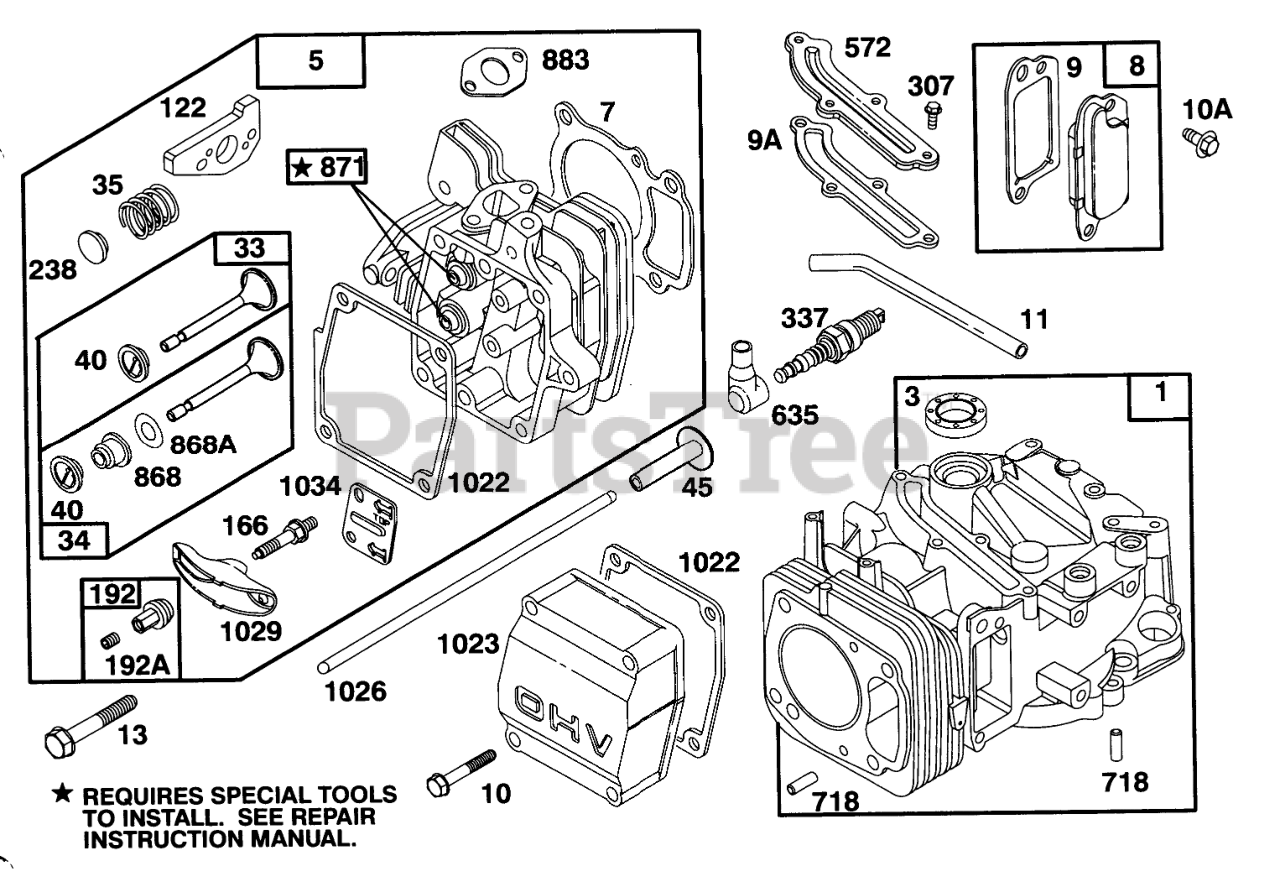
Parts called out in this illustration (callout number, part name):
1	CYLINDER ASSEMBLY
3	SEAL - OIL
5	CYLINDER HEAD
7	CYLINDER HEAD GASKET
8	BREATHER ASM
9	BREATHER GASKET
9A	GASKET-BREATHER
10	HEX HEAD SCREW
10A	HEX HEAD SCREW
11	TUBE - BREATHER
13	CYLINDER HEAD SCREW
33	EXHAUST VALVE
34	INTAKE VALVE
35	VALVE SPRING
40	SPRING RETAINER
45	VALVE TAPPET
122	ADAPTER ASSEMBLY
166	ROCKER ARM STUD
192	Ball & Screw-Rocker Arm (Incl. Ref. #192A)
192A	Screw-Set
238	VALVE CAP
307	SCREW - SEM
337	PLUG-SPARK
572	BAFFLE - CYCLINDER
635	SPARK PLUG ELBOW
718	DOWEL - SLEEVE
868	SealAssy-Valve
868A	Seal-Valve
871	Bushing-Guide
883	EXHAUST GASKET
1022	ROCKER COVER GASKET
1023	COVER - VALVE
1026	PUSH ROD
1029	ROCKER ARM
1034	PUSH ROD GUIDE
